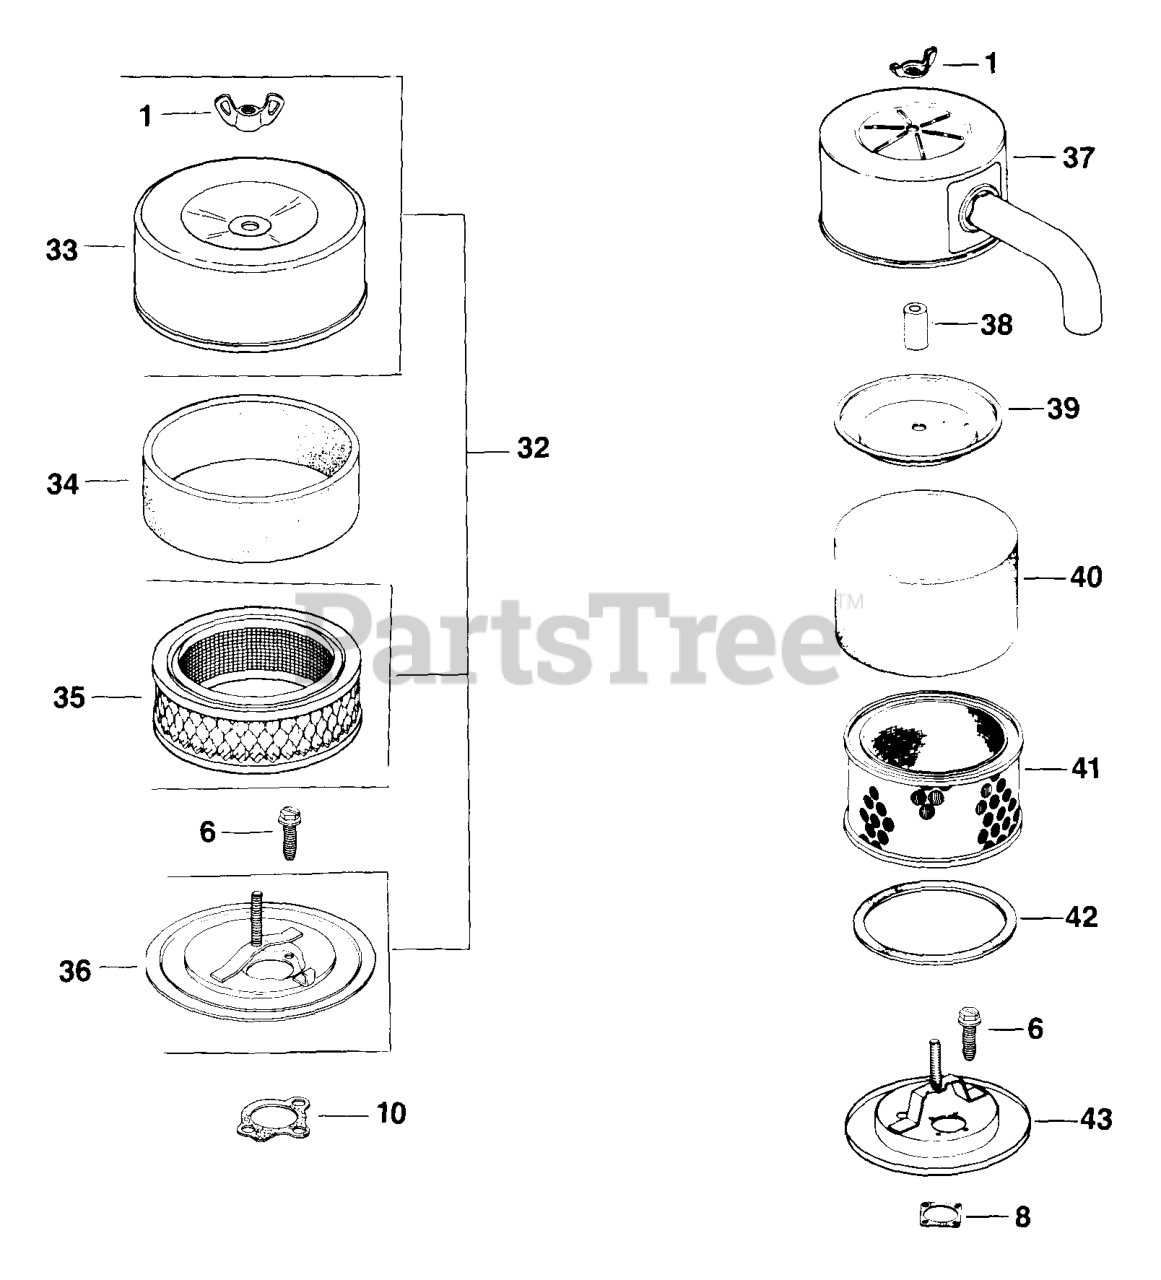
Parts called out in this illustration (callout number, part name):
1	NUT, WING 1/4-20 USE 25 100 15-S
6	SCREW, WSH HD TAP #10-32X7/16" USE 25 086 101-S
8	GASKET, AIR CLEANER
10	GASKET, AIR CLEANER ELBOW
32	CLEANER - DISCONTINUED
33	COVER, AIR CLEANER - DISCONTINUED
34	PRE-CLEANER USE 237421-S
35	AIR FILTER/PRE-CLEANER KIT USE 25 883 03-S1
36	BASE, AIR CLEANER - DISCONTINUED
2511307-S	DECAL, AIR CLEANER - DISCONTINUED
